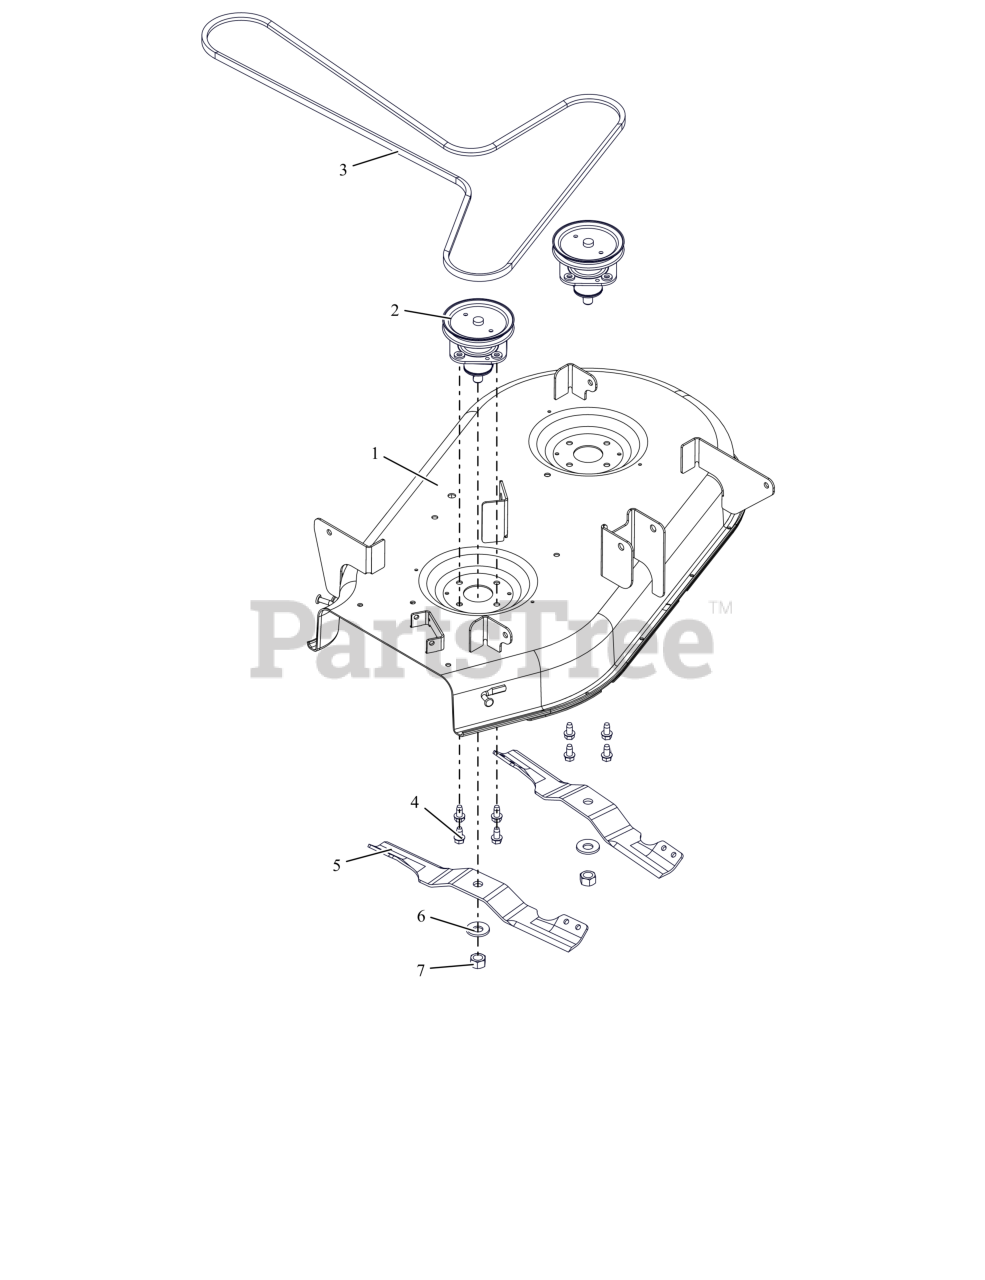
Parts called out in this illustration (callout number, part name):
1	KIT- 34" EDGE DECK W/DECALS
2	KIT, DECK SPINDLE ASM (34/50)
3	V-BELT, HA-WRAPPED
4	SCR,TAP .375-16X.75 HWH TR ZCC
5	BLADE, MOWER 17.35
6	WSHR-BLVL .669X1.535X.138
7	NUT-STD .625-18 ZCC
